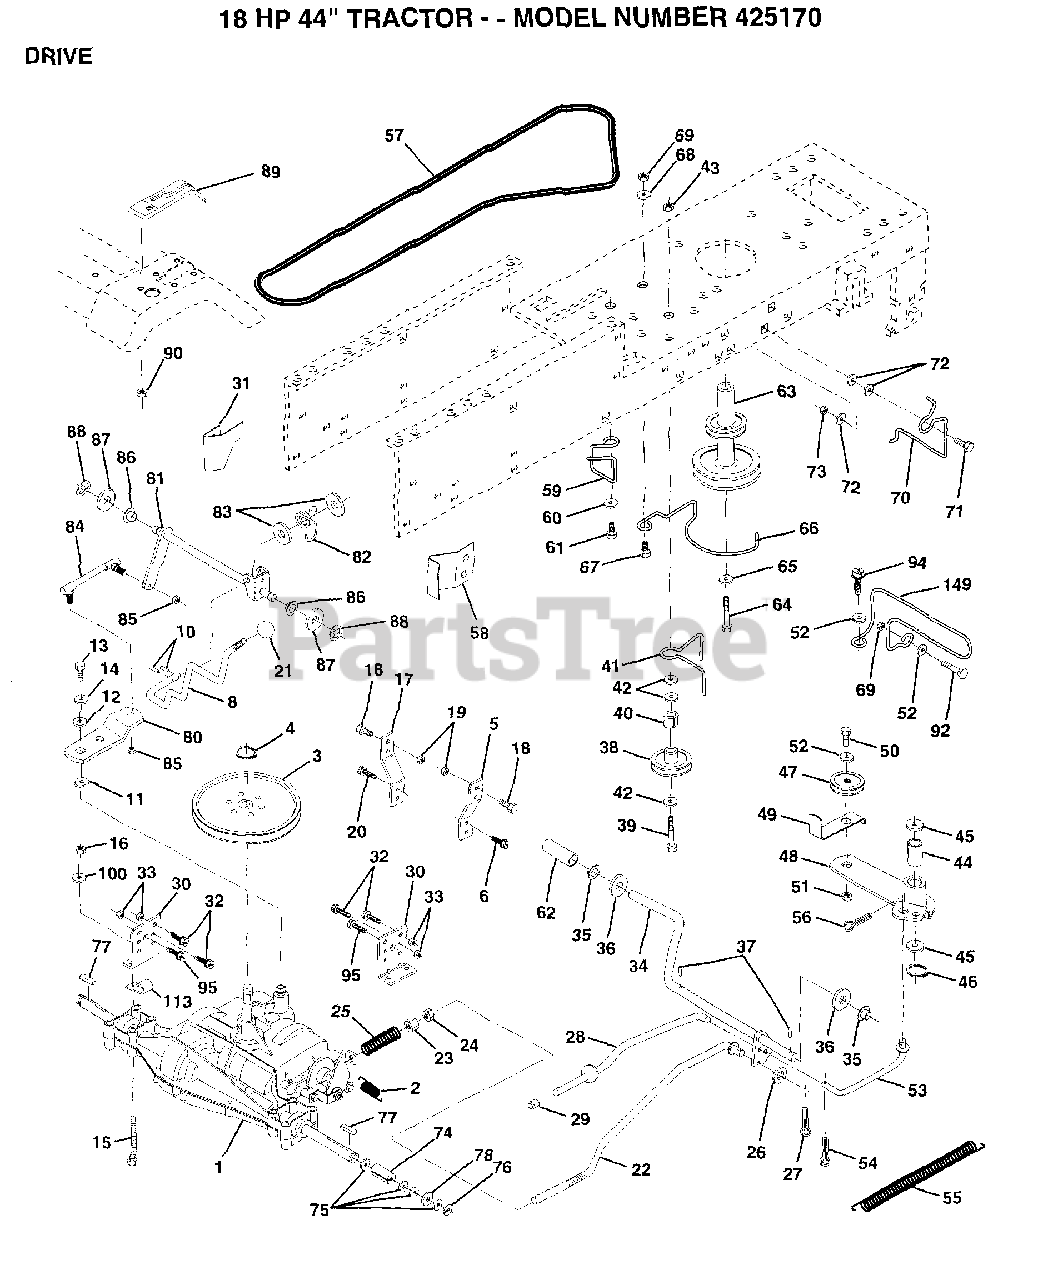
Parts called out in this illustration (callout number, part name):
3	PULLEY TRANS
5	STRAP TORQUE
6	SCREW
8	ROD SHIFT FEND LT
10	PIN COTTER 1/8
11	WASH-SHFT PLT LT
12	WASHER
14	LOCKWASHER
16	NUT
17	STRAP TORQUE
18	BOLT
19	NUT
20	SCREW
21	KNOB T (1/2-HOLE)
22	BRAKE ROD
23	NUT
24	NUT
25	SPRING ROD LT
26	WASHER
27	COTTER PIN
28	BRAKE PARK ROD
29	PLUNGER CAP T
30	TRANSAXLE MTG BKT
31	TRANSAXLE MTG BKT
31	"KEEPER,BELT LH T"
32	BOLT
33	NUT
35	NYLON BEARING
36	WASHER LT
38	PULLEY.IDLER.FLAT
39	BOLT
40	SPACER T
41	BELT KEEPER LT
42	WASHER
43	NUT
44	"LY, BEARING"
45	WASHER LT
46	KLIP RING
48	ARM IDLER
49	RETAIN BELT
52	WASHER HYT
53	"LINK, CLUTCH T"
54	COTTER PIN
55	"SPRING, RETURN LT"
56	COTTER PIN
58	"KEEPER,BELT RH T"
59	KEEPER BELT CNTSP
60	WASHER
61	SCREW
62	PEDAL COVER T
63	PULLEY.ENGINE
64	BOLT
65	LOCKWASHER
66	KEEPER.BELT.ENG.L
67	BOLT
68	WASHER
70	KEEPER BELT ENG
71	BOLT
72	WASHER
74	SPACER LT
75	WASHER
76	E-RING LT
77	SQUARE KEY
78	SQUARE KEY
78	WASHER
80	ARM SHIFT TRANS
81	SHAFT ASM.SHIFT
82	"SPRING,TORSION"
83	WASHER
84	TIE ROD
85	NUT 1/4-28
86	BUSHING
87	WASHER D
88	KLIP RING
90	NUT
92	BOLT D
94	SCREW GTV
95	SCREW
100	WASHER M
113	CLIP T
115	BOLT HEX
149	MUFFLER GUARD
